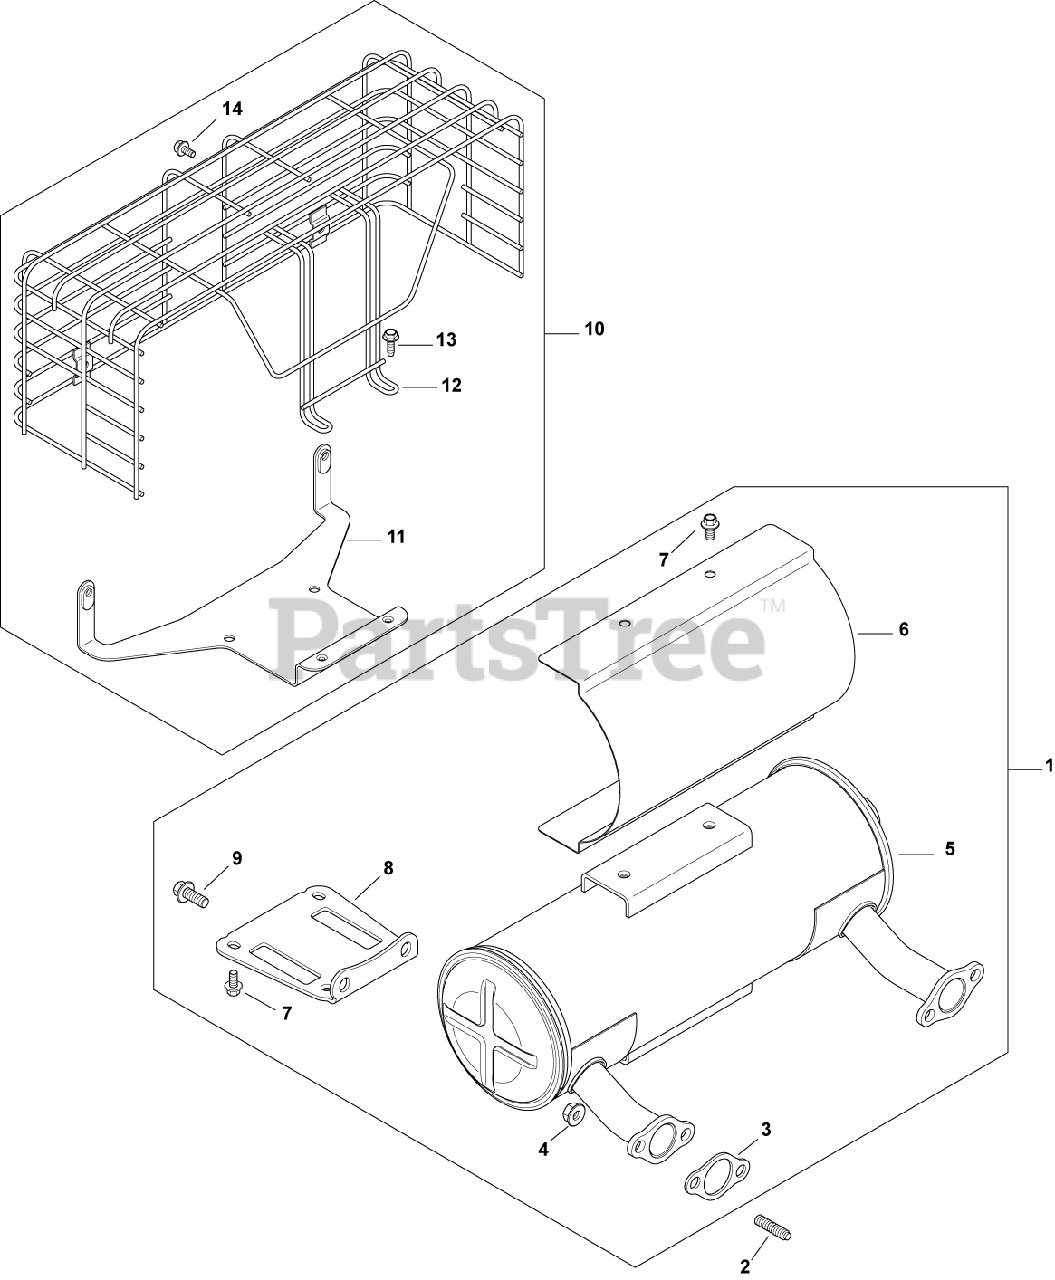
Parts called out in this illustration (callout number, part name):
1	MUFFLER KIT, STARTER SIDE/STRAIGHT
2	STUD, EXHAUST-USE 25 072 24-S
3	GASKET, EXHAUST
4	NUT, FLG M8X1.25
5	MUFFLER, STARTER SIDE/STRAIGHT USE 24 068 141-S
6	SHIELD, ALUM HEAT (LH/CH TWIN)
7	SCREW, FLG M6X1.0X12
8	BRACKET, MUFFLER
9	SCREW, FLG M8X1.25X20
10	KIT, MUFFLER GUARD
11	BRACKET, EXHAUST GUARD
12	GUARD, MUFFLER
13	SCREW,FLG THD FRM M5X0.8X16-(#25086398S)
14	SCREW, HVY FLG M5X.8X10
